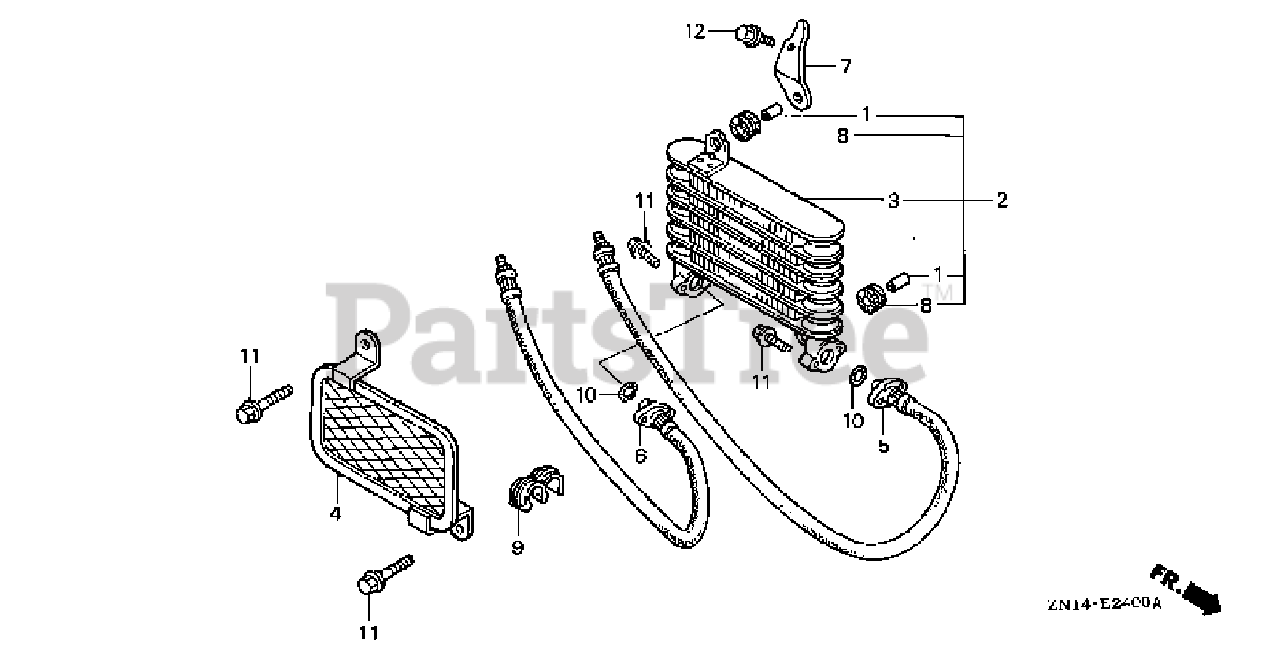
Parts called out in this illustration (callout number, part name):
1	COLLAR (12MM)
2	COOLER ASSY., OIL
3	COOLER, OIL
4	GRILLE, OIL COOLER
5	HOSE A, OIL
6	HOSE B, OIL
7	STAY, OIL COOLER
8	RUBBER, RADIATOR MOUNTING
9	CLAMP, HOSE (D13.5)
10	O-RING (10X2.6)
11	BOLT, FLANGE (6X22)
12	BOLT, FLANGE (6X14)
